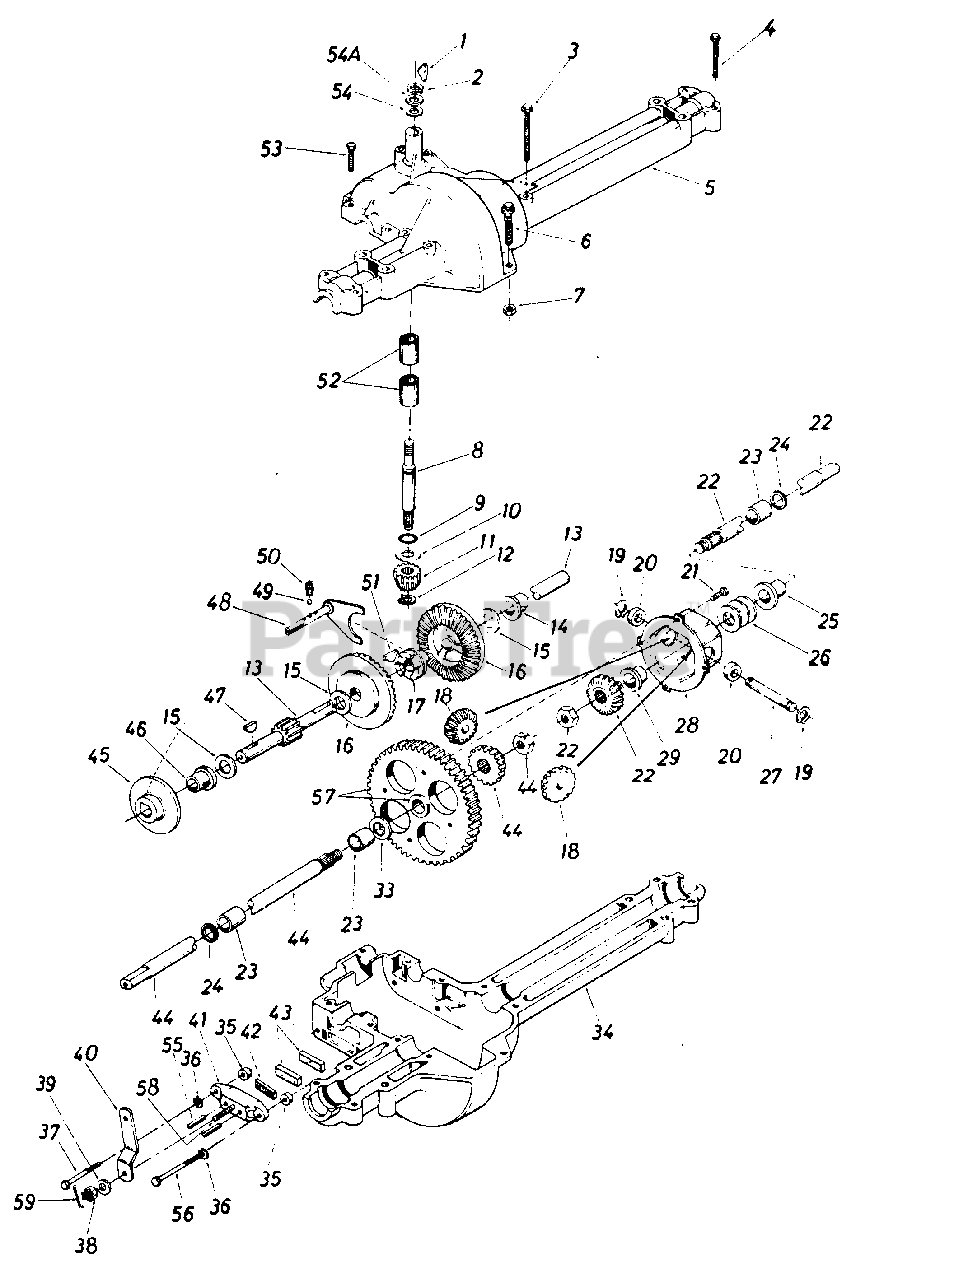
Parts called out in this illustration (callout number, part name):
1	#4 Hi-Pro Key 3/32 x 5/8" Dia.
2	Snap Ring .625n Shaft
3	Hex Bolt 1/4-20 x 1.75" Lg.
4	Hex Bolt 5/16-18 x 25"
5	Upper Housing
6	Hex Fl-Bolt 1/4-20 x .88" Lg.
7	Hex Nut 1/4-20 Thd.
8	Input Shaft
9	Square Seal 5/8n I.D.
10	Thrust Washer 5/8" I.D. x 1.25" O.D.
11	Pinion Input 14T
12	Retaining Ring 7/16" Ext.
14	Flange Brg. 5/8" I.D. x 3/4"
15	Fl-Wash.
16	Bevel Gear 42T
17	Clutch Collar
18	Miter Gear 15T
19	Snap Ring
20	Thrust Bearing 1/2" I.D. x 1.0" O.D.
21	Pan Head Scr. 1/4-20 x .50" Lg. w/Patch
22	Axle R.H. Ass'y.-Kit
23	Sleeve Bearing 3/4" I.D. x 1.0 Lg
24	Oil Seal 3/4" I.D.
25	Flange Bearing 3/4" l.D. x 15/1 6" Lg.
26	Fl-Wash. .760n l.D. x 1.49" O.D.
27	Cross Shaft
28	Differential Housing Ass'y.
33	Fl-Wash. .760" I.D. x 1.49" O.D.
34	Lower Housing
35	Spacer .53" O.D. x 3/8" Lg.
36	L-Wash. 1/4" I.D.
37	Hex Bolt 1/4-20 x 1.50" Lg. (Grade 5)
38	Castle Nut 5/16-24 Thd.
39	Fl-Wash. .344" I.D. x .875" O.D.
40	Actuating Arm
42	Puck Plate
43	Brake Puck
44	Axle L.H. Ass'y.-Kit
46	Flange Bearing 5/8" I.D. x 15/16" Lg.
47	Woodruff Key 3/16 x 5/8 HT
48	Shift Fork Ass'y.
49	Ball Detent .250" Dia.
50	Spring Detent
51	#9 Hi-Pro Key 3/16" x 3/4" Dia. HT
52	Needle Brg. 5/8" I.D. x 1/2" Lg.
53	Hex Bolt 1/4-20 x 1.00" Lg.
54	Fl-Wash. 5/8" I.D. x .030
54A	Fl-Wash. 5/8" l.D. x .040
55	Actuating Pin 5/16" Dia.
56	Hex Bolt 1/4-20 x 2.50" Lg. (Grade 5)
57	Differential Gear 72T Ass'y. w/Bearing
58	Sq. Hd. Bolt 5/16-24 Thd.
59	Cotter Pin 3/32" Dia. x .50 Lg.
